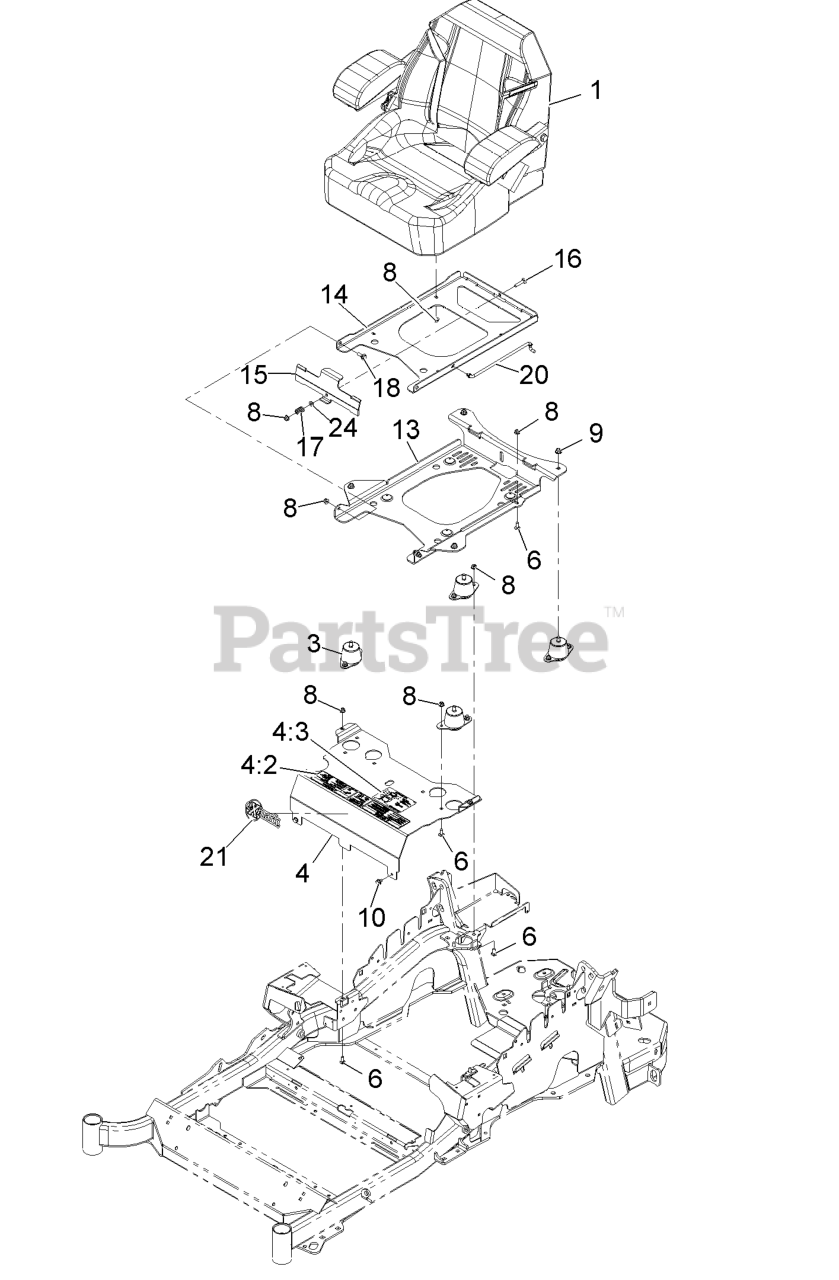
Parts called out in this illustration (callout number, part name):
3	ISOLATOR-SEAT
4	MOUNT-SEAT
4:2	DECAL-CONSOLE
4:3	DECAL-SERVICE AID
6	SCREW-CARR
8	NUT-HF, NI
9	NUT-HF, NI
13	PLATE-SUPPORT, SEAT TILT
14	PLATE-FRAME, SEAT TILT
15	PLATE-LATCH, SEAT
16	BOLT-CARR
17	SPRING-COMPRESSION
18	SCREW-SHOULDER
20	ROD-PROP
24	WASHER-PLAIN
